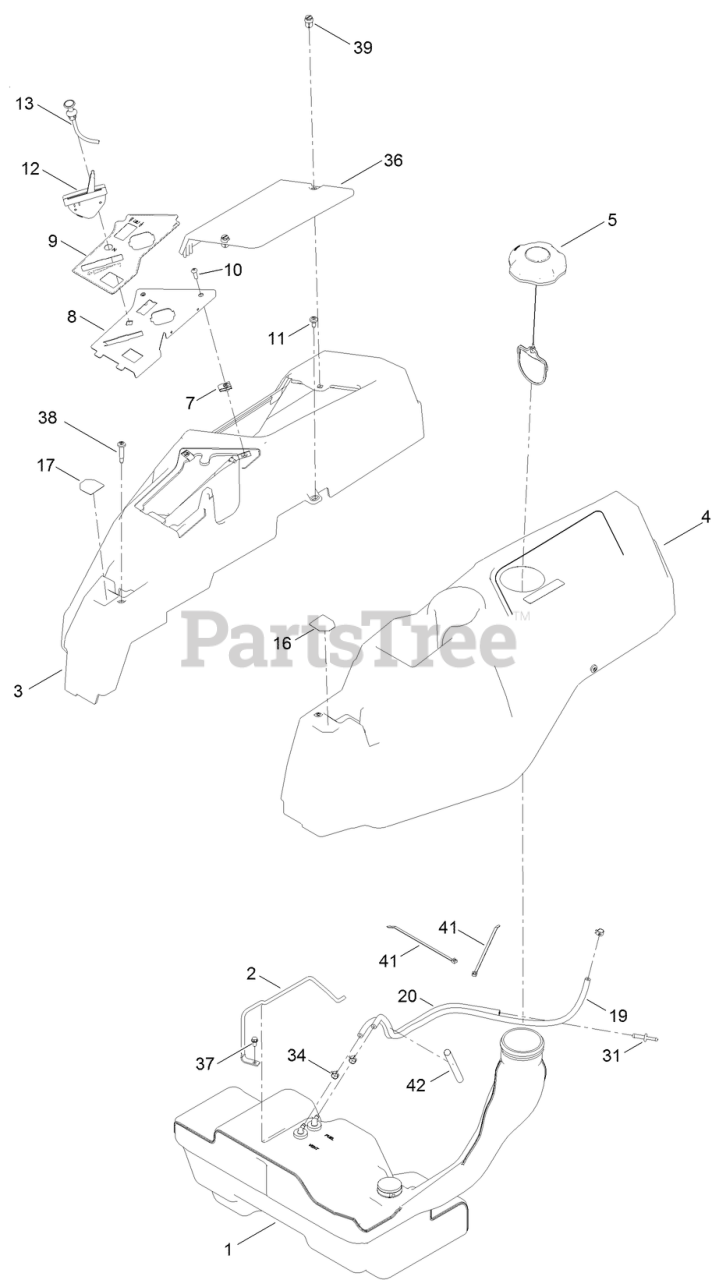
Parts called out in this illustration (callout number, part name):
1	TANK-FUEL ASM
2	ROD-HOLD DOWN
3	POD-RH
4	POD-LH
5	CAP-FUEL, RATCHETING
8	PANEL-CONTROL
9	DECAL-PANEL, CONTROL
10	SCREW-PRH
11	SCREW-SHOULDER
12	CABLE-THROTTLE
13	CABLE-CHOKE
16	DECAL-LEVER, CONTROL (LH)
17	DECAL-LEVER, CONTROL (RH)
19	HOSE-FUEL
20	HOSE-VENT
31	ADAPTER ORIFICE
34	CLAMP-HOSE
36	COVER-BATTERY
37	SCREW-HWH
38	SCREW-SHOULDER
39	FASTENER
41	TIE-CABLE
42	SLEEVE-FUEL LINE PROTECTOR
